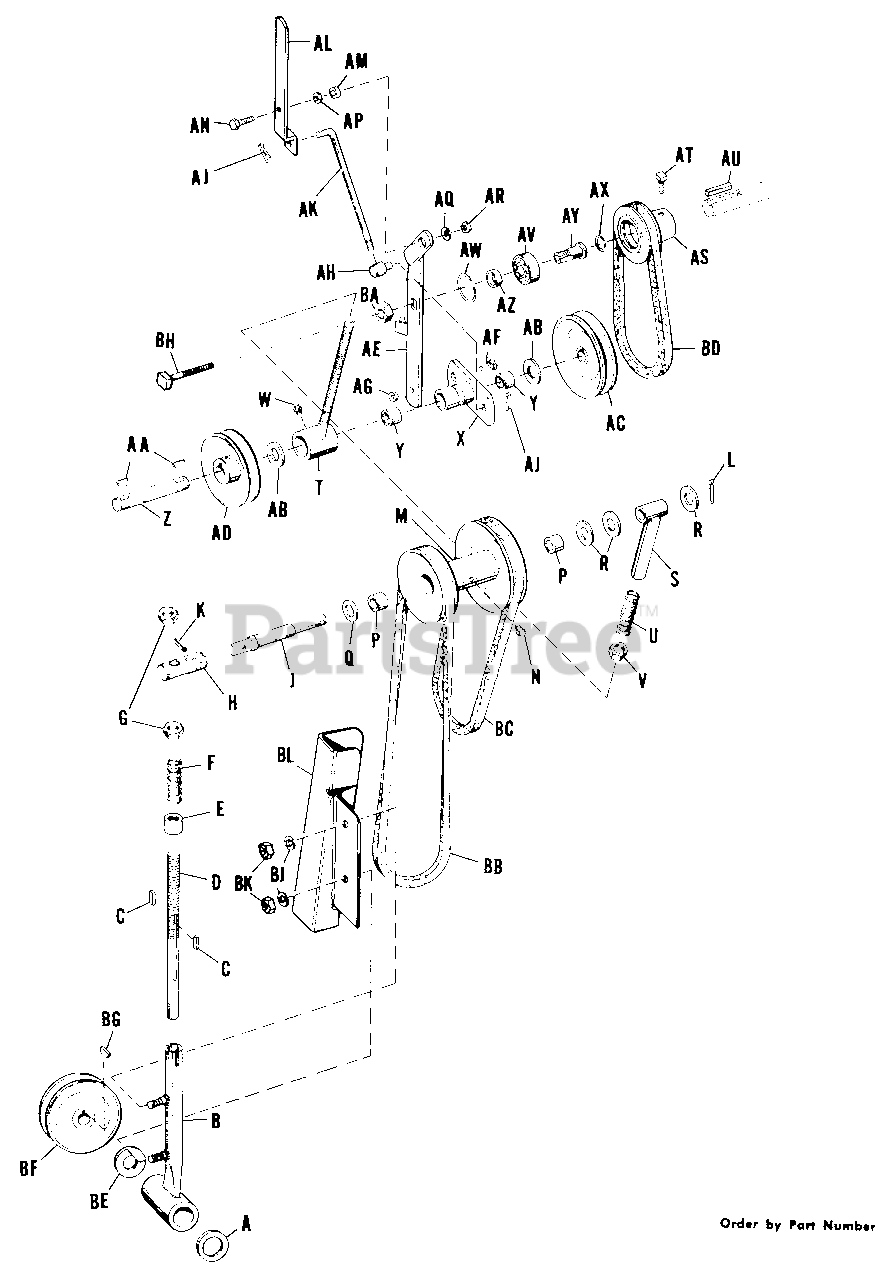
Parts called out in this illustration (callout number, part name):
B	Post Assy., Pulley
G	Nut, Hex, Jam, 5/8"-11 N. C.
H	Pivot, Pulley Post
J	Shaft, Pulley
K	Pin, Roll, 5/16" x 1" lg.
L	Pin, Cotter 3/16" x 1-1/4" lg.
M	Pulley Assy.
N	Fitting, Grease
P	Bearing, Needle
S	Post Assy., Pulley
T	Screw Assy., Belt Tension
V	Nut, Hex, Jam, 5/8"-11 N. C.
W	Fitting, Grease
X	Flange Assy.
Y	Bearing, Needle
AA	Key, Woodruff
AE	Arm Assy., Pulley
AF	Bolt, Carriage, 3/8"-16 N. C. x 1 1/4" lg.
AG	Nut, Hex, Full Lock, 3/8"-16 N. C., Elastic Stop Nut
AH	Pivot, Adj. Rod
AJ	Pin, Cotter, 3/32" x 5/8" lg.
AK	Rod, Adj.
AL	Lever, Belt Release
AN	Screw, Hex Hd. Cap, 3/8"-16 N. C. x 1" lg.
AP	Washer, Plain, 5/16"
AQ	Washer, Lock, 3/8"
AR	Nut, Hex, Full, 3/8"-16 N. C.
AS	Pulley, Engine
AT	Screw, Sq. Hd., Cup Point, Set, 5/16"-18 N. C. x 1/2" lg.
AV	Bearing, Ball
AW	Ring, Retaining
AX	Ring, Retaining
AY	Pin, Bearing
BA	Nut, Hex, Jam, Lock, 3/4"-16 N. F.
BD	Belt, "V"
BG	Key, Woodruff
BH	Capscrew, 3/8- 16 N. C. x 3-1/2" lg., minimum thread length 2- 1/2"
BJ	Washer, Lock, 3/8"
BK	Nut, Hex, Full, 3/8"-16 NC
BL	Guard, Belt
